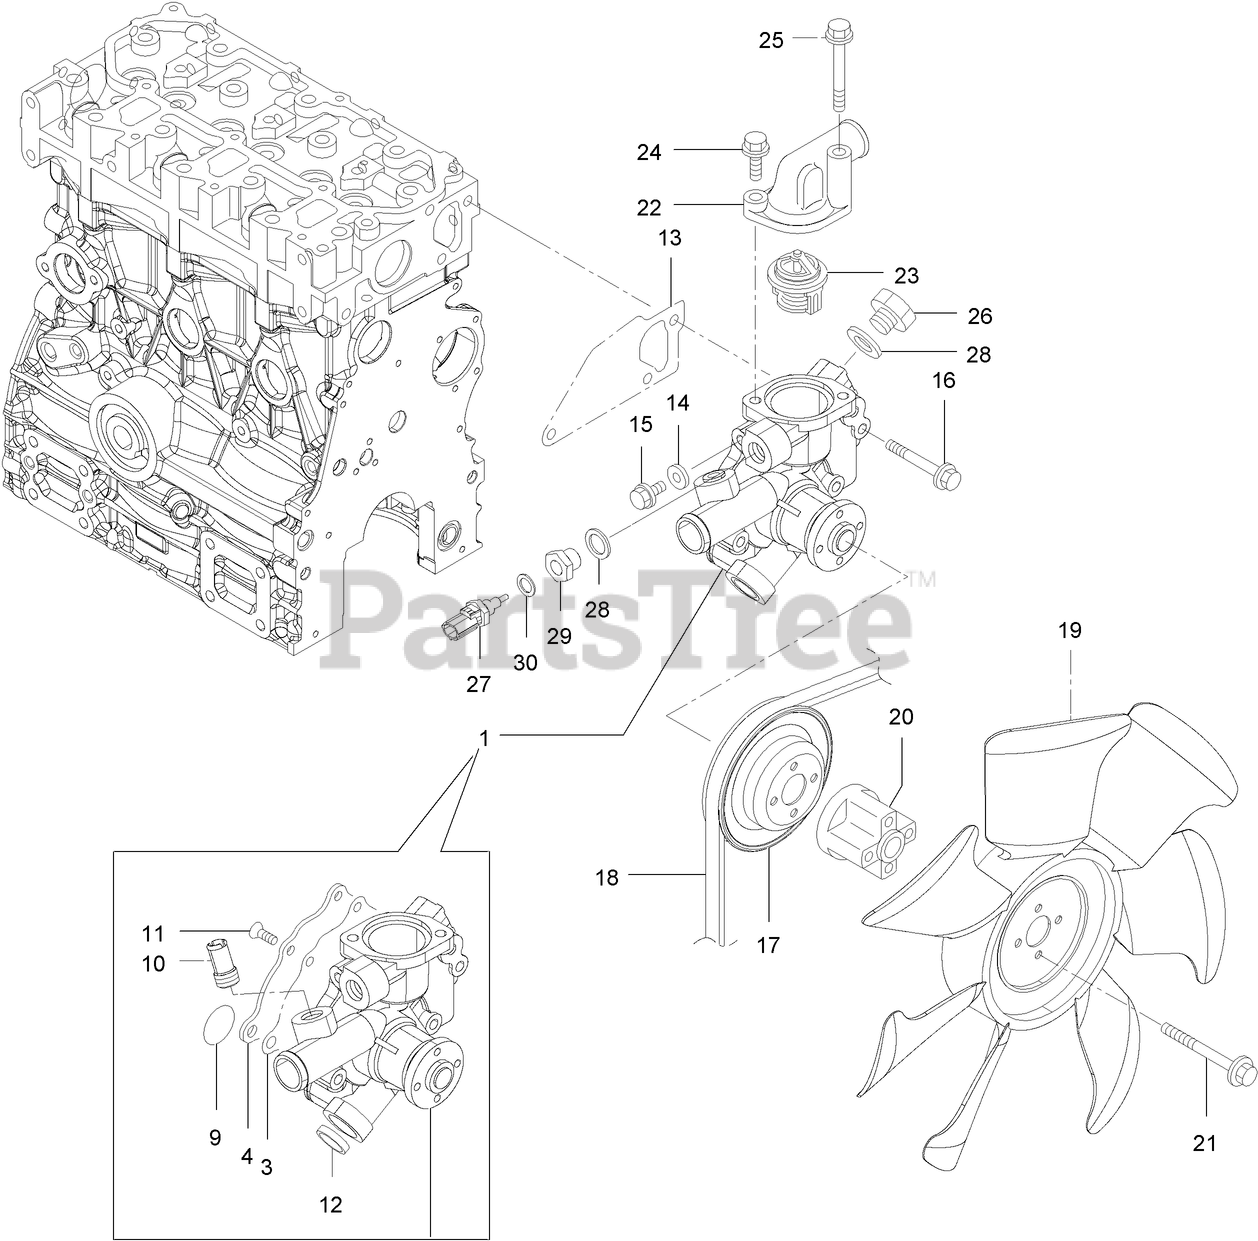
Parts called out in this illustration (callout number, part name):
1	PUMP ASM-WATER
10	JOINT-PIPE
13	GASKET-WATER PUMP
17	V-PULLEY
19	FAN-COOLING 1
20	SPACER-FAN
22	COVER-THERMOSTAT
23	THERMOSTAT
27	SENSOR-THERMOSTAT, CW
30	WASHER-SEAL
